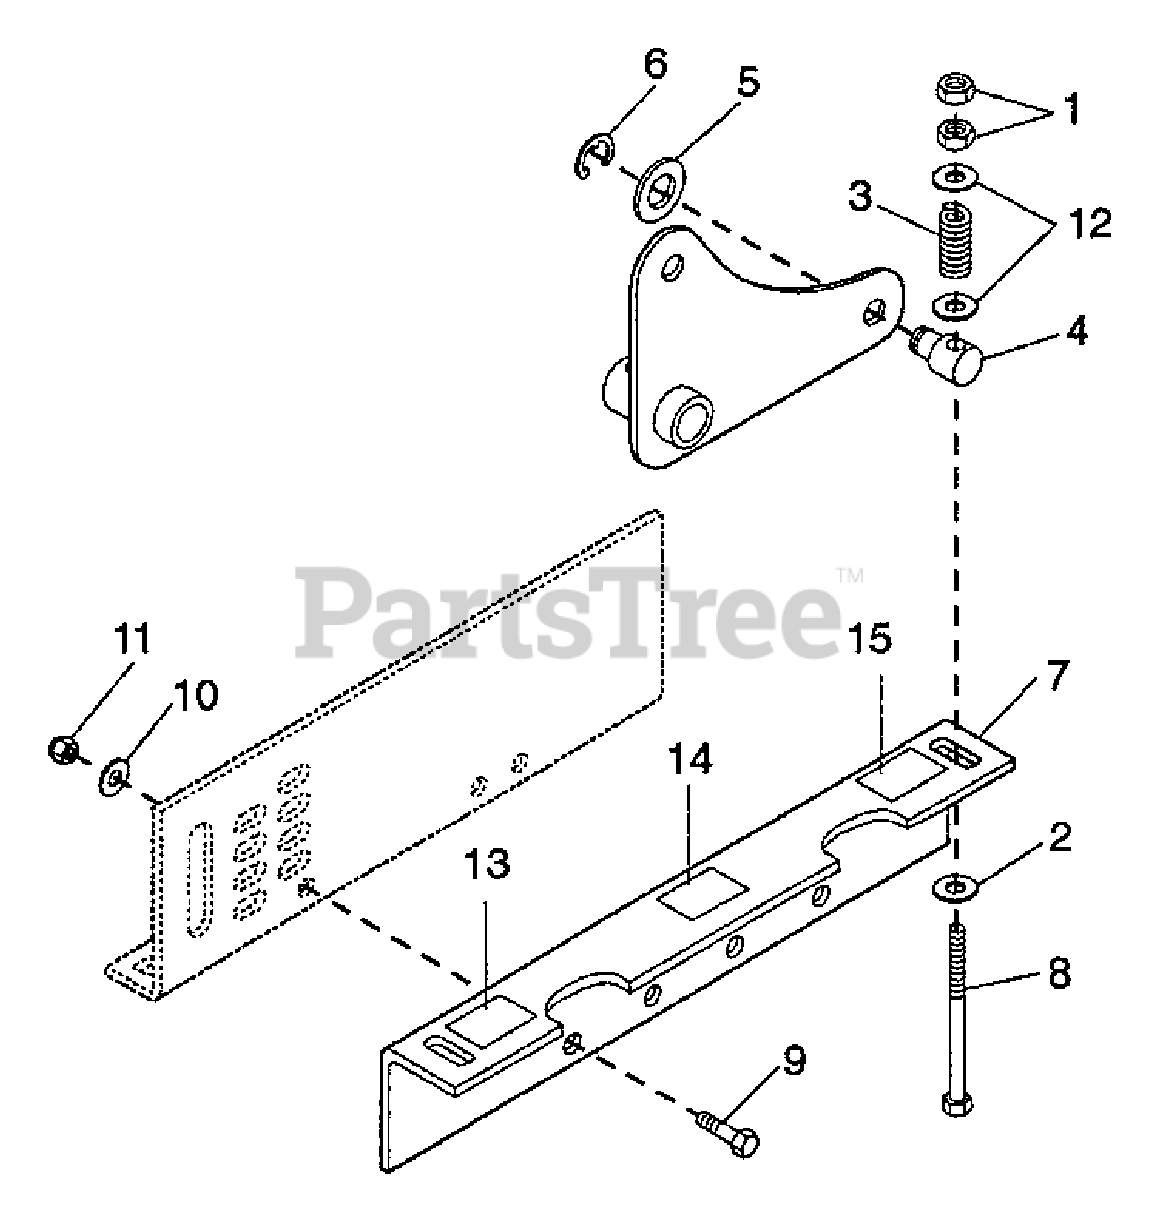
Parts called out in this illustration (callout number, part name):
1	Nut-Jam .50-13 Grade 2
2	Washer-Flat-Steel .563 x 1.375 x .109
3	Spring-Compression .125 x .78 x 1.00
4	Pivot, Mower Lift
5	Washer-Flat-Steel .656 x 1.312 x .095
6	Ring-Retaining-External .750 x .050
7	Lift Bracket
8	Bolt-Hex .50-13 x 6.50
9	Bolt-Hex .38-16 x 1.50 Grade 5
10	Washer-Flat-Steel .438 x 1.0 x .083
11	Nut-Locking-Nylon .375-16 Grade 2
12	Washer-Flat-Steel .531 x 1.062 x .095
13	Decal, Warning Eye
14	Decal, Danger Hand
15	Decal - Warning
